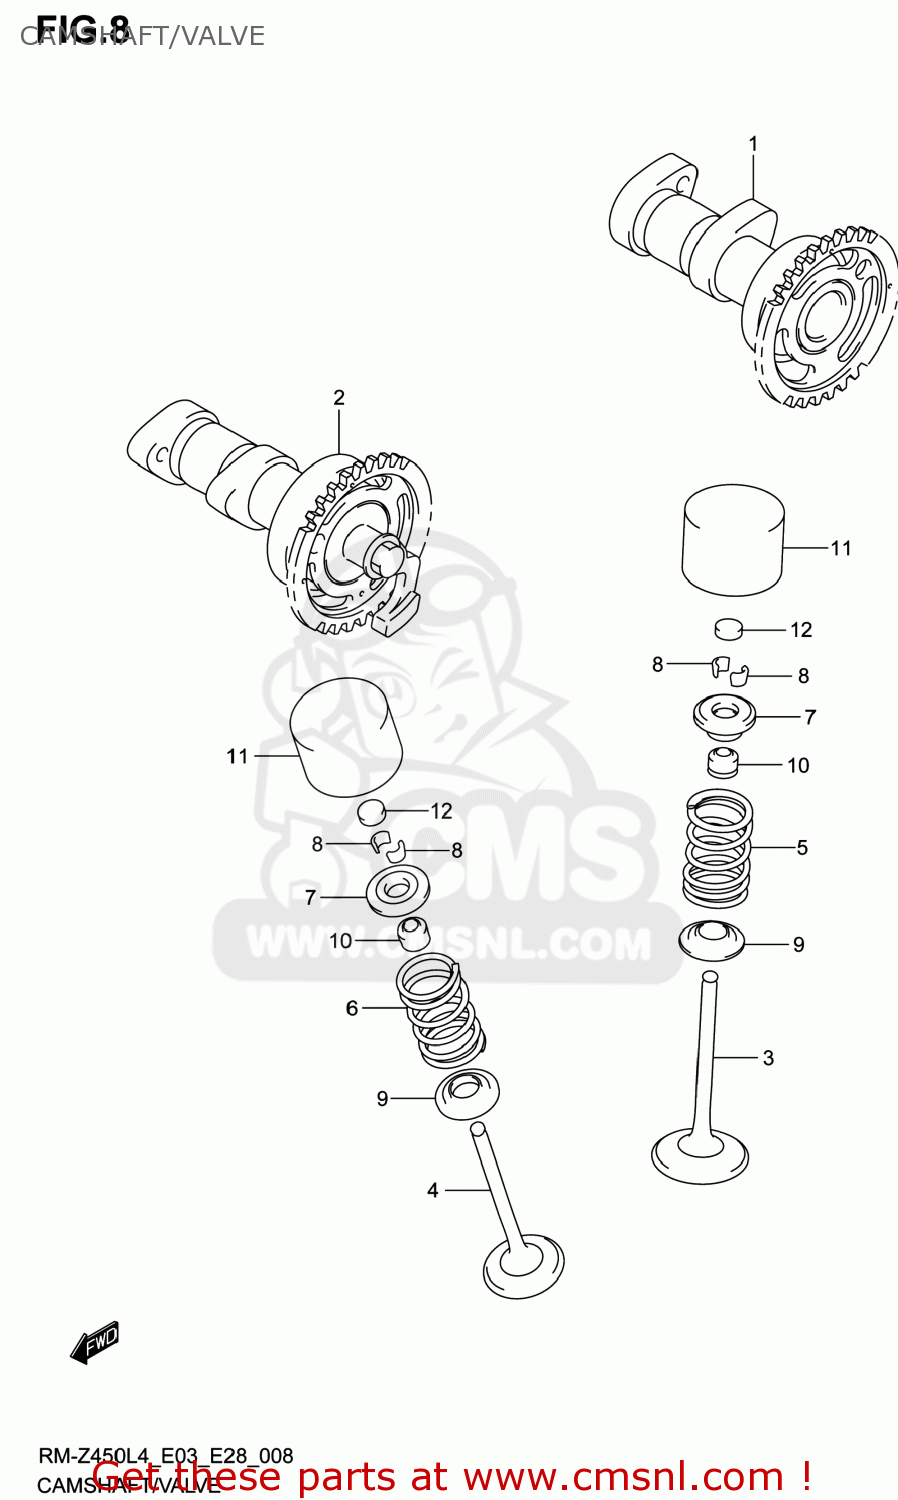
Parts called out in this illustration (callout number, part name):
1	CAMSHAFT,INTAKE
2	CAMSHAFT,EXHAUST
3	VALVE,INTAKE
4	VALVE,EXHAUST
5	SPRING,VALVE
6	SPRING,VALVE
7	RETAINER,VALVE SPRING
8	COTTER,VALVE
9	SEAT,VALVE SPRING
10	SEAL,OIL(5.5X11X8.2)
11	TAPPET
12	SHIM,TAPPET
13	SHIM SET,TAPPET
14	CASE,TAPPET SHIM
